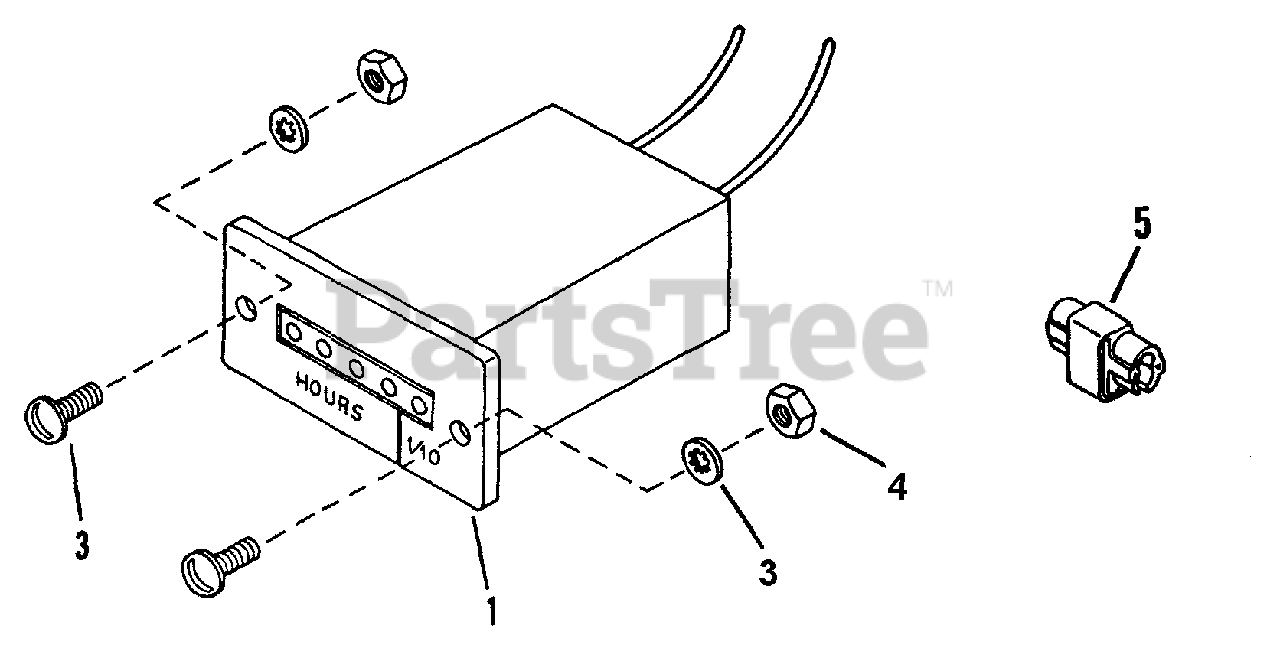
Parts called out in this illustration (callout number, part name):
1	HOURMETER
2	SCREW, #6-32x3/4" Round Head Machine
3	WASHER, #6 Internal Tooth Lock
4	NUT, #6-32 Hex
5	CONNECTOR, Wire
